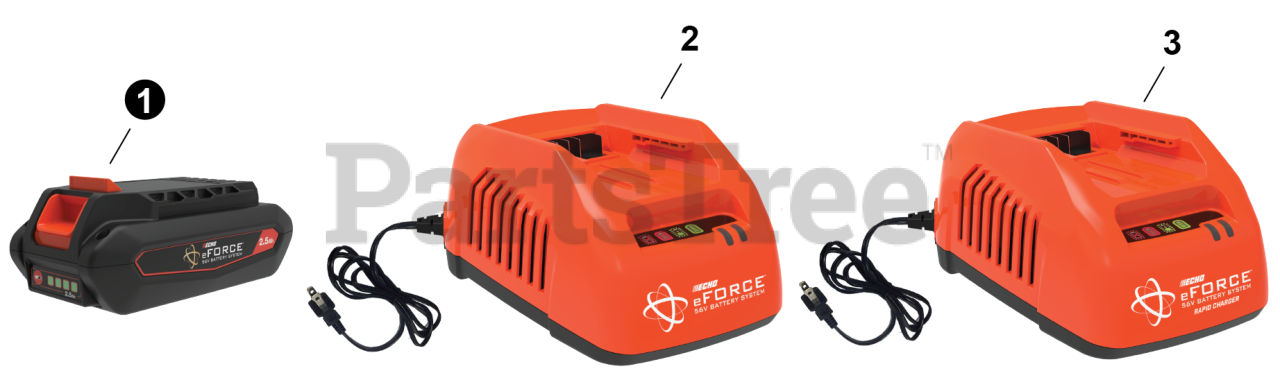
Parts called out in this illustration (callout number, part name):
1	BATTERY, 56V LITHIUM-ION - 2.5Ah
2	CHARGER, BATTERY STANDARD 56V
3	CHARGER, BATTERY RAPID 56V
